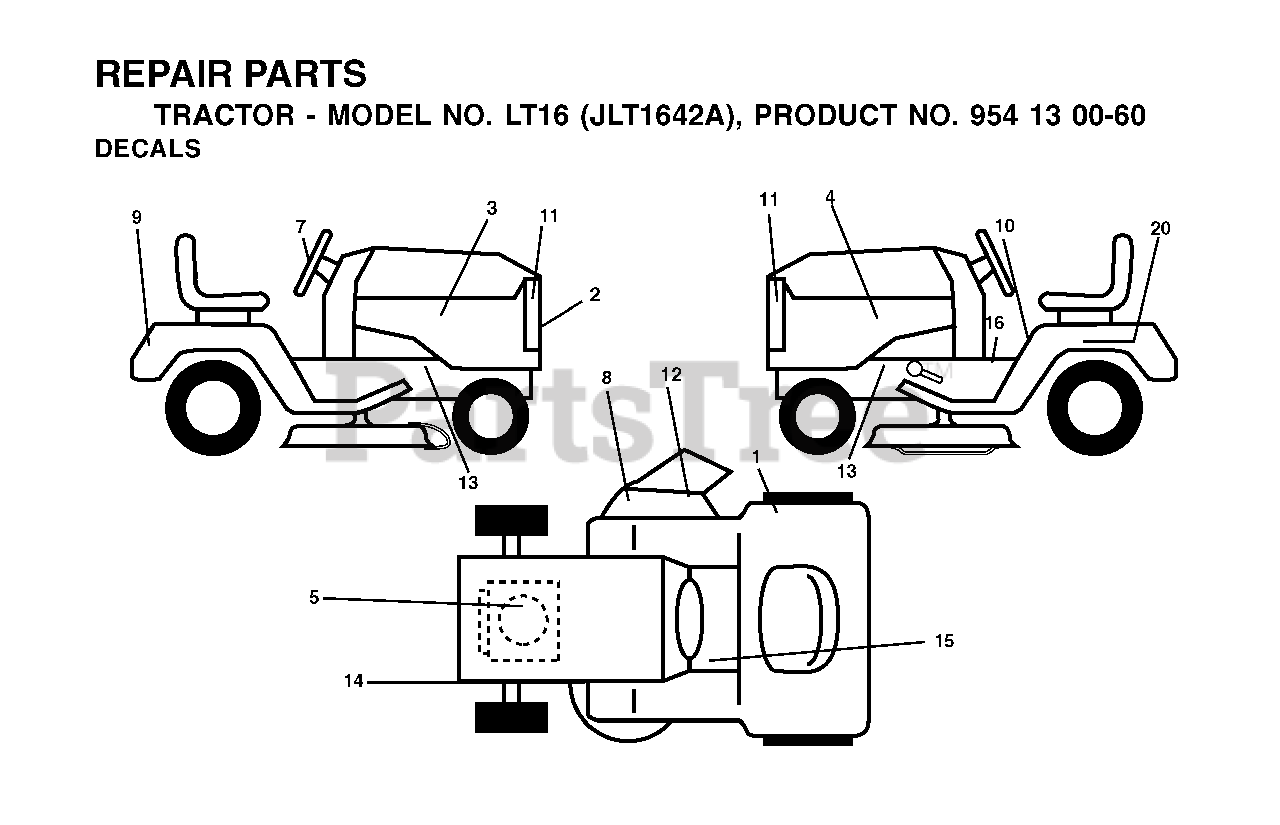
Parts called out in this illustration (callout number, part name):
8	DECAL.INTERNATIONL.CUTFINGER
10	DECAL READ OWNER'S MAN SYMS
12	DECAL DECK "B" 42"
14	DECAL V BELT SCHEMATIC
16	DECAL PARK BRAKE
20	DECAL BTRY SYMBOLS
